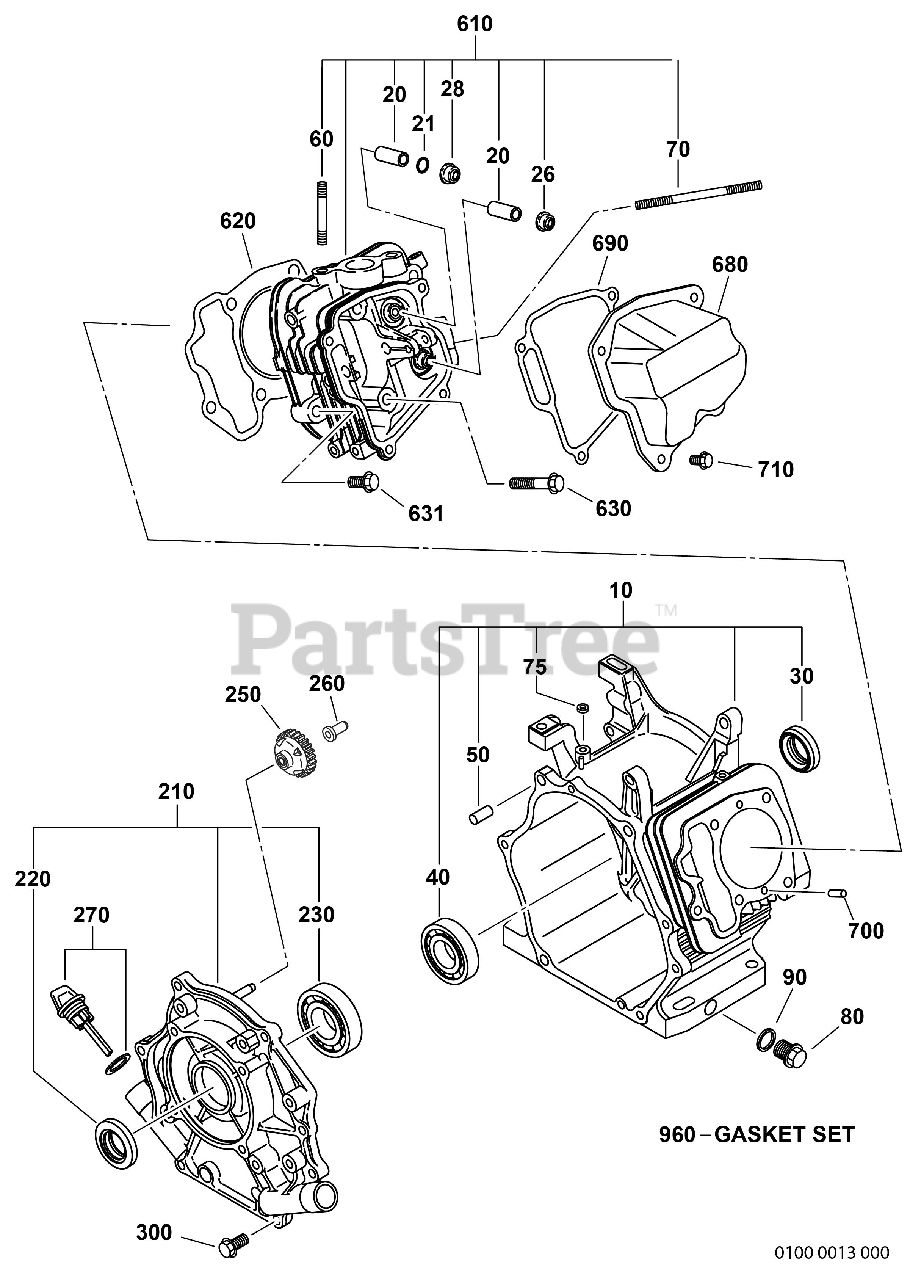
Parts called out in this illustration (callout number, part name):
10	CRANK CASE CP
26	SEAL-EXH VALVE
28	RETAINER PLATE
210	MAINBEARING COVER CP
250	GOVERNOR GEAR CP
260	GOVERNOR SLEEVE
610	CYLINDER HEAD AY
680	ROCKER COVER CP
690	GASKET(ROCKER COVER)
